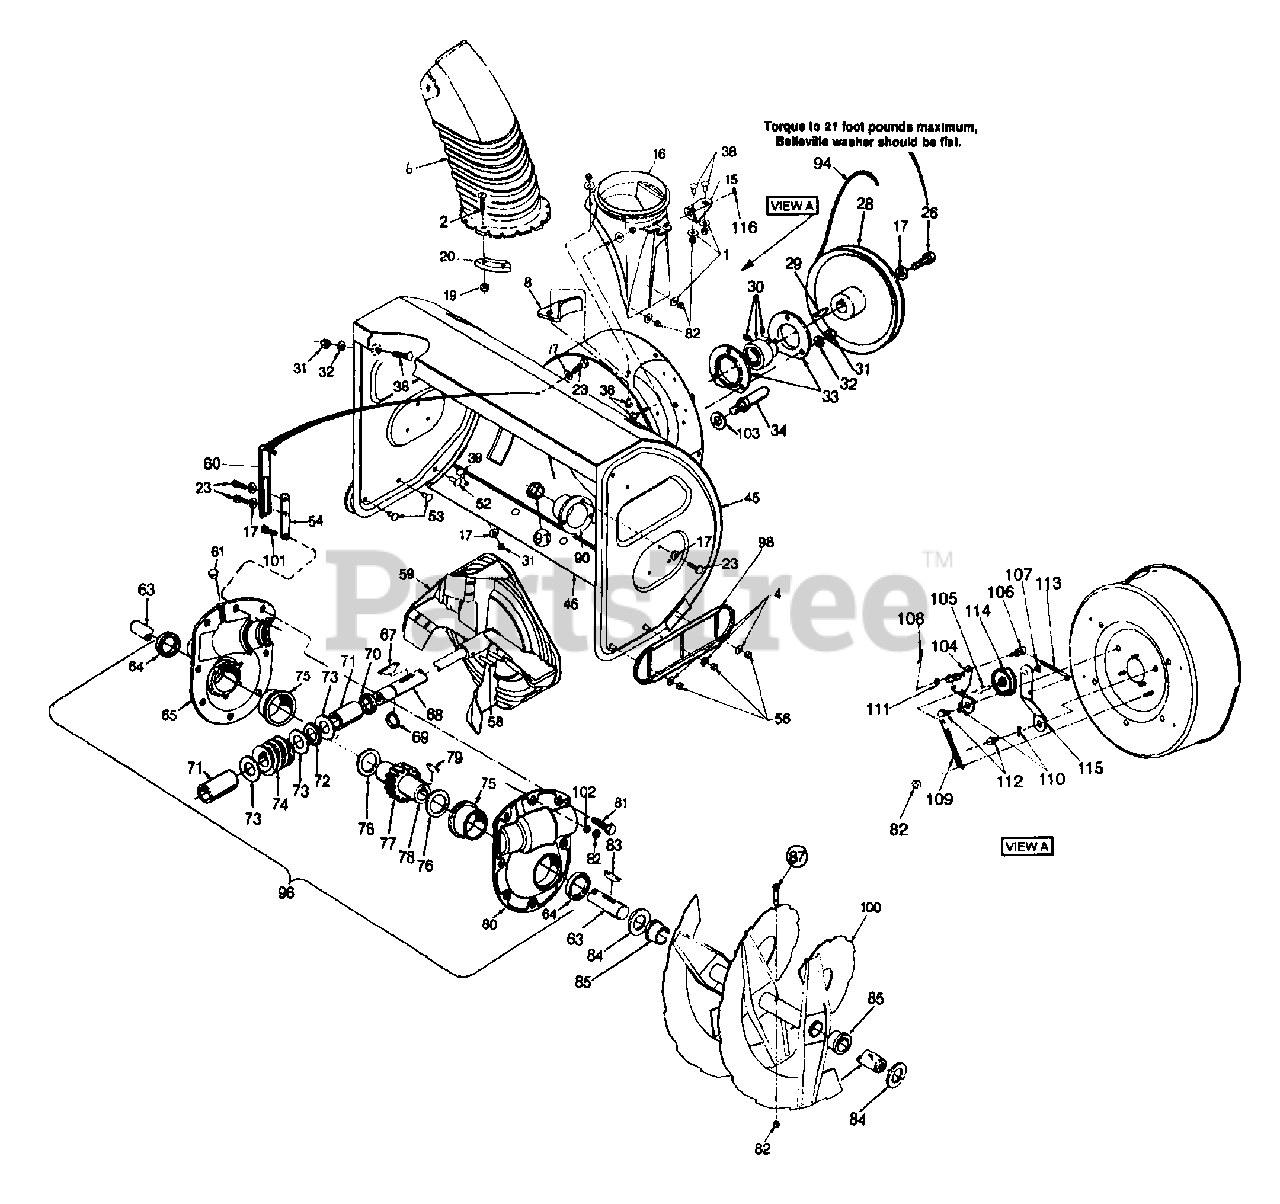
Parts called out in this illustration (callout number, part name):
1	Flat Washer .344 I.D. x .875 O.D.
2	Truss. Hd. Mach. Scr. 1/4-20 x .75
4	Bell. Washer
6	6" Lower Chute Remote Tilt
8	Chute Bracket
15	Chute Bracket
16	Chute Adapter
17	Bell. Washer.345 I.D. x.88 O.D. x.06
19	Hex Cent. L-Nut 1/4-20 w/ Flange
20	Chute Flange Keeper
23	Hex Wash HD Self-Tap Scr 5/16-18 x .75
26	Hex Screw 5/16-18 x .75
28	1/2" V-Pulley .875 I.D. x 10.12 O.D.
29	#9 Hi-Pro Key 3/16 x 3/4 Dia HT
30	Self-Aligning Bearing .875 I.D.
31	Hex Nut 5/16-18 Gr. 5
32	L-Wash 5/16 I.D.
33	Bearing Housing
34	Belt Keeper Studs 3/8-16 x 2.75
38	Carriage Bolt 5/16-18 x .75
46	Shave Plate 33"
52	Carriage Bolt 3/8-16 x 1.00 Gr. 5
53	Carriage Bolt 3/8-16 x .75" Lg.
54	Gear Housing Support Plate 1 x 3/16
56	Hex Jam Nut 3/8-16
58	Spring Spiral Pin Heavy 5/16 dia x 1.7 2
59	Blower Fan Ass'y Complete
60	Gear housing Support Bracket 1 x 3/16
61	Barbed Plug
63	Spiral Axle -33"
64	Oil Seal 1.50 ID Garlock (76 x 6223)
65	Gear Housing Half - RH
67	#9 Hi-Pro Key 3/16 x 3/4 dia HT
68	Auger Control Shaft
69	Snap Ring for .875 dia. shaft
70	Oil Seal for .875 I.D. (76 x 6133)
71	Sleeve Bearing .875 I.D.
72	Thrust Bearing .88 I.D. x 1.44 O.D. x .078 1
73	Flat Washer .88 I.D. x 1.4 O.D. x .125
74	Worm Gear L.H. Double Thread
75	Flange Brg. 1.5 I.D. x 1.75 O.D. x .80
76	Flat Washer 1.5 I.D. x 2.0 O.D. x .03
77	Worm Gear LH Double Thread (Bronze)
78	Worm Gear Shaft
79	#91 Woodruff Key 1/4 x 3/4 dia
80	Gear Housing Half L.H.
81	Hex Flange Scr. 5/16-18 x .75
82	Hex Ins. L-Nut 5/16-18
83	#91 Woodruff Key 1/4 x 3/4 dia
84	Flat Wash.
85	Flange Bearing
87	Shear Bolt 5/16-18 x 1.75
90	Housing bearing 1.5 Dbl D
91	Flange Bearing w/flats
94	V-Belt 1/2 x 44 LG
96	Worm Gear Box Ass'y
100	RH Spiral Ass'y Serrated - 33"
100	LH Spiral Ass'y Serrated - 33"
101	Hex Scr 5/16-18 x 1.25
102	5/16 Sprg Wash.
103	3/8 Sprg Lock Wash.
104	Brkt Ass'y Brkt
105	Scr Hex Cap 3/8-24 x 1.5 Gr. 5
106	Adjustment Ferrule
107	Hex Ins L-Nut 3/8-24
108	Intern Cot-Pin 5/16 dia
109	Spr Extn .470 dia x 4.75 Lg
110	Wave Washer.66 ID x.88 O.D.
111	Fl-Wash SAE .34 x .68
112	Shld Scr .625 dia x .170 x .062
113	Rod Idler Auger
114	3.0 OD Flat Idler with Flanges
115	Brkt Idlr Auger
116	Plastic Bushing .380 I.D.
